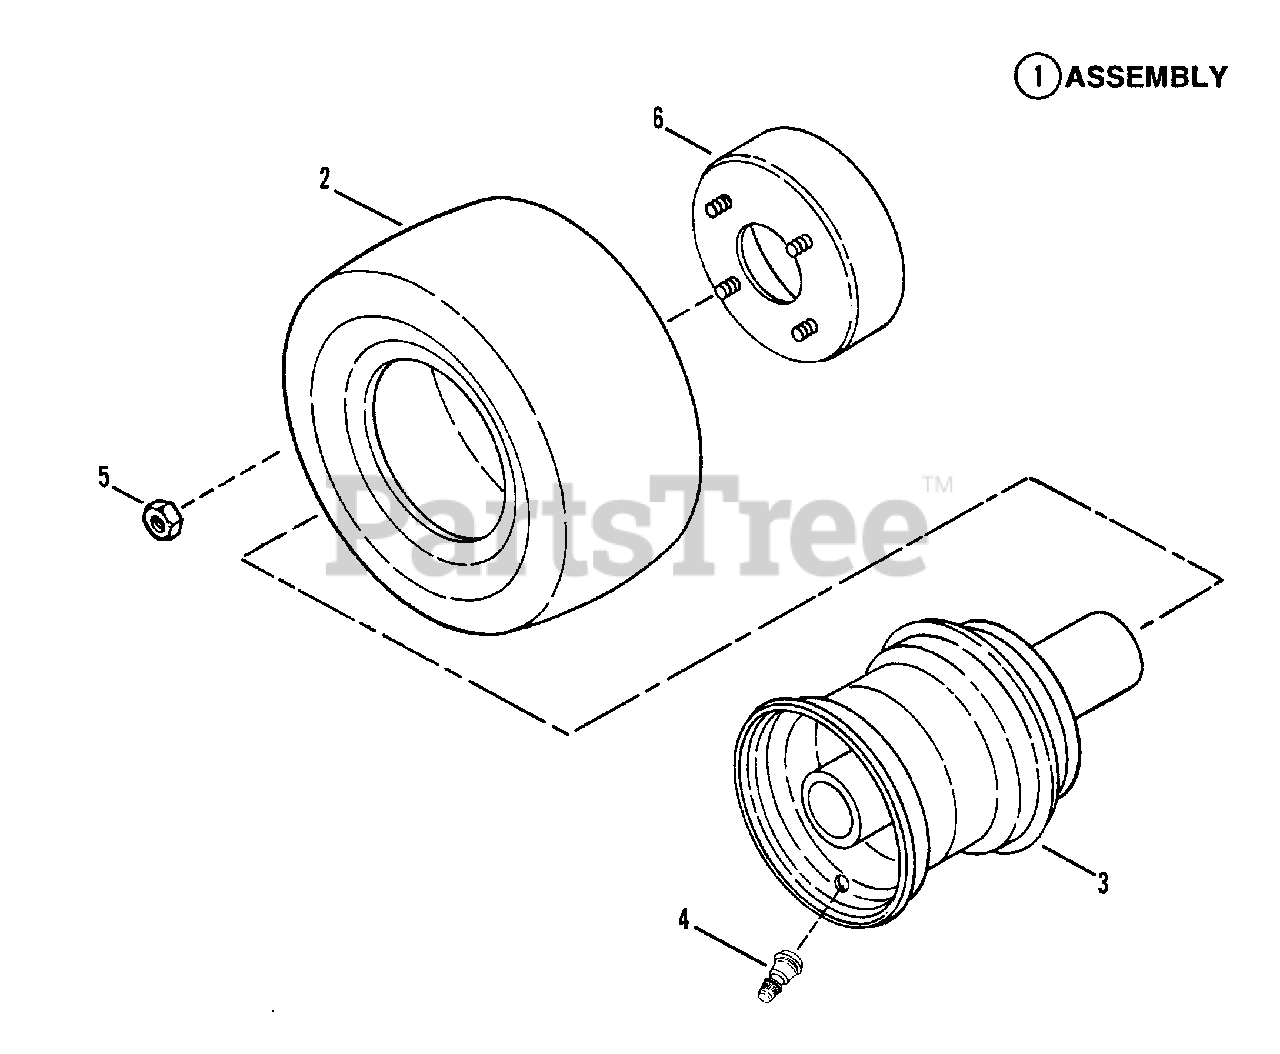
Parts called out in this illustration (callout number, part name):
1	ASSEMBLY, Rear Tire & Rim
2	TIRE, Rear, 16-650 x 8, 4-Ply Tubeless
3	RIM
4	VALVE, Air (Snap-in)
5	LUG-NUT
